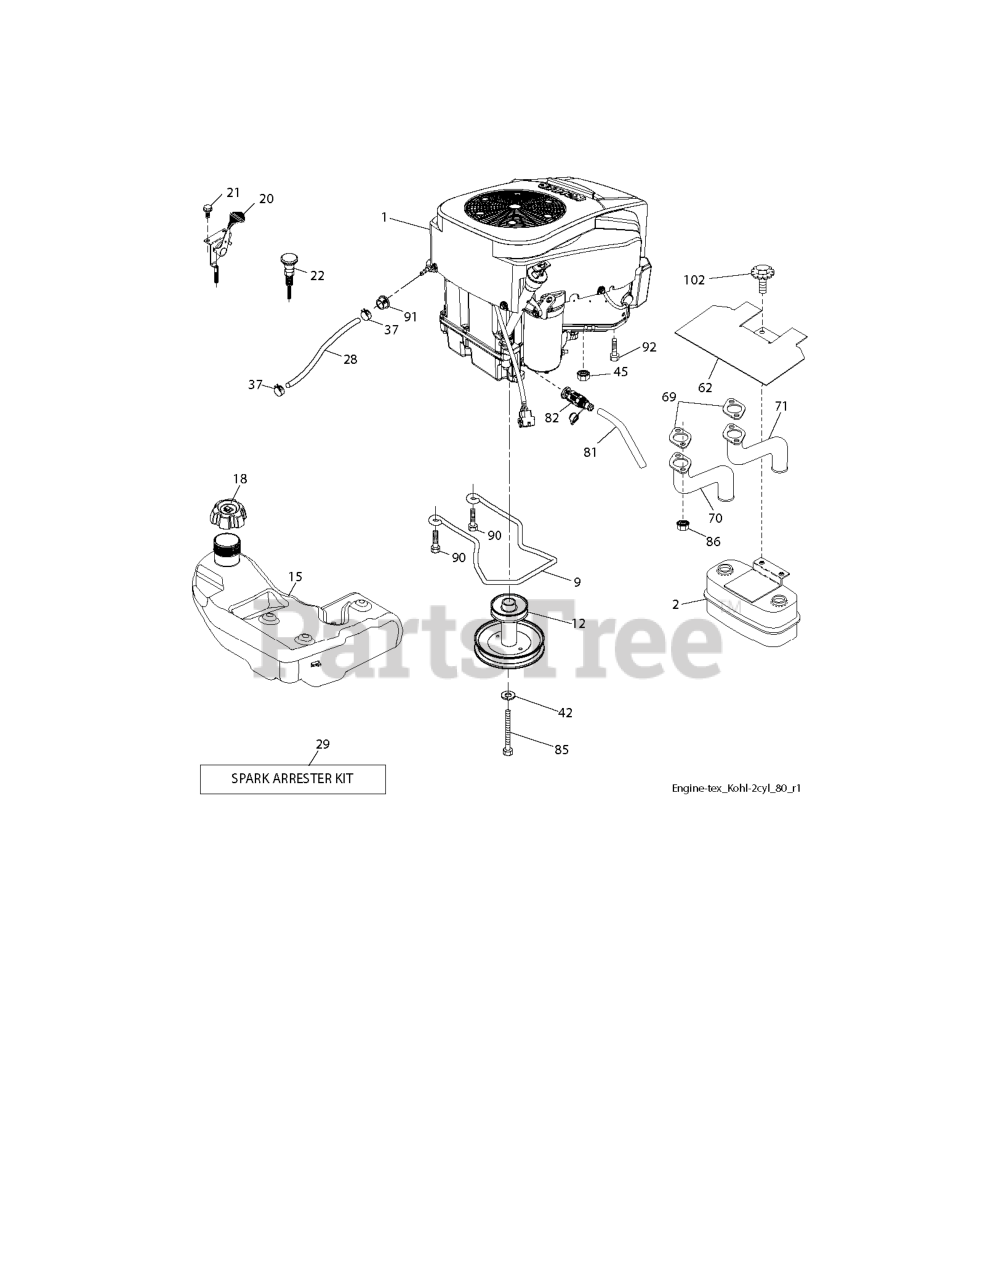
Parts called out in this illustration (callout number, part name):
2	MUFFLER.ASM.TWIN.MNTG.BRACKET
12	PULLEY.ENGINE
15	FUEL TANKS
18	FUEL CAP
18	CAP ASSY FUEL 3" GRAY
20	THROTTLE CONTROL
22	CONTROL.CHOKE.ERGO.PUSH-IN.BLA
28	LINE.FUEL.64"REAR.EMIS
29	KIT.SPARK ARRESTOR 794945 B&S
37	HOSE CLAMP
62	SHIELD.HEAT.MUFFLER
69	GASKET.EXHAUST.KOHL.CV18-CV26
70	PIPE.EXHAUST.RH.CV18/20
71	PIPE.EXHAUST.LH.CV18/20
81	TUBE, DRAIN OIL ASM.
82	VALUE.OIL.DRAIN
85	BOLT.HEX.7/16-20X4.GR5.1.5BLUE
86	NUT.HEX.FLANGE.TOPLOCK
90	SCREW 3/8-16X1
91	BUSHING.1.375OD
92	SCREW 3/8-16X1
102	SCREW
